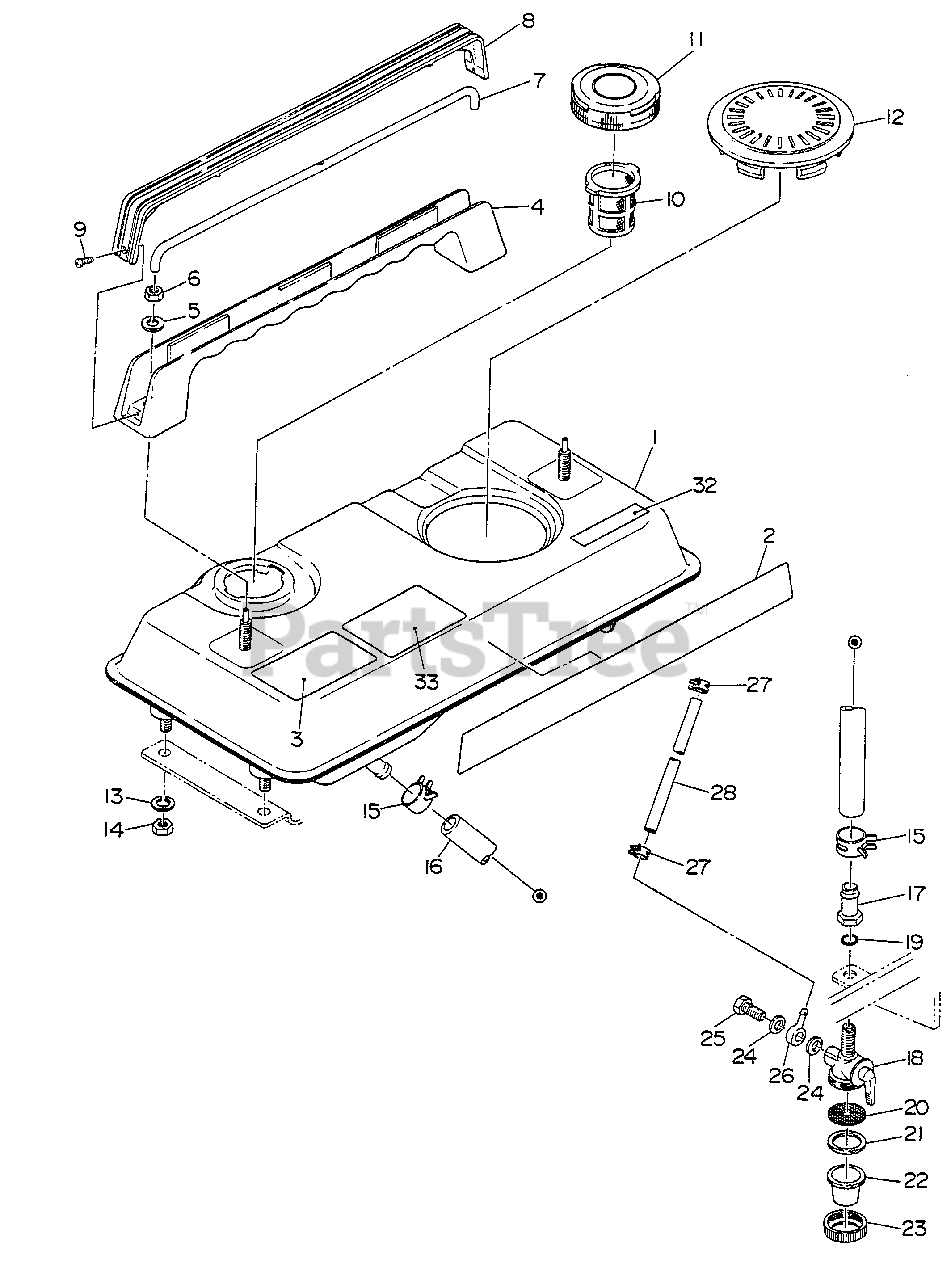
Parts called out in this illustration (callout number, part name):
1	FUEL TANK ASSY
2	LABEL, MODEL EG-1200
3	LABEL - GENERATOR
4	HANDLE
5	LOCKWASHER
6	NUT
7	PIPE - BREATHER
8	COVER, HANDLE
9	SCREW
10	FILTER, FUEL
11	CAP ASSY
12	COVER
13	LOCKWASHER
14	NUT
15	CLAMP, HOSE
16	RUBBER PIPE (11.5 X 17.5 X 230mm)
17	CONNECTOR
18	FILTER, FUEL
19	O-RING
24	WASHER
26	BOLT, BANJO
27	CLAMP, HOSE
28	RUBBER PIPE (6 X 12 X 160mm)
32	LABEL - SPARK ARRESTER
33	LABEL - DANGER
